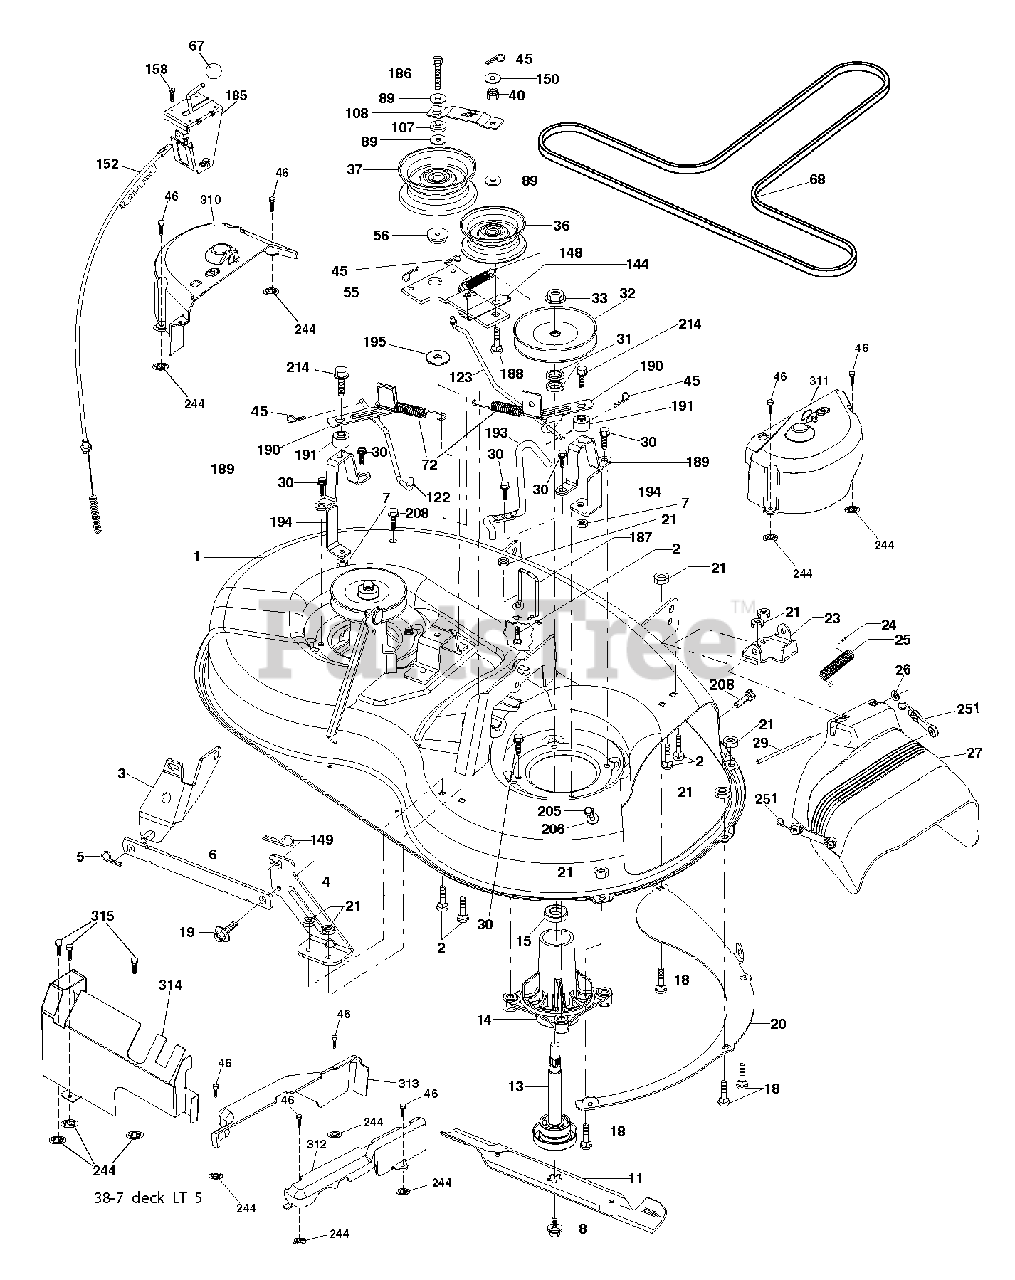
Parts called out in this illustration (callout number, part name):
1	DECK SVC 38/94 192556X431
2	BOLT 5/16-18 X3/4 ZN/YEL GR 5
3	BRKT ASM SWAY BAR
4	BRACKET DECK SWAY BAR 38"/42"
5	Retainer Spring
6	BAR SWAY DECK
7	NUT.71038.31-18.HEX.NYLOCK
8	BOLT.WASHER.ASM.7/16-2
11	BLADE 38" PREMIUM
13	SHAFT.ASM.MDRL.N/GREASE.38
14	HOUSING.MANDREL.4PT.
18	BOLT
19	BOLT SHD 5/16-18
20	BAFFLE.VORTEX.FRONT.38"
21	LOCKNUT
23	BRKT.DEFLECTOR.38"2005+
24	CAP-SLEEVE LT
25	SPRING.TORSION.DEFLECT
26	NUT PUSH M
27	SHIELD ASM.DFLCTR MWR.38-7"BLK
29	ROD.HINGE
30	SCREW, WASHER HEAD
31	WASHER.SPACER.MANDREL
32	PULLEY MANDREL
33	NUT.FLANGE.LOCK.TOP
36	FLAT IDLER PULLEY
37	PULLEY.IDLER.FLAT.UNPLATED
45	RETAINER M
46	SCREW.1/4-20X5/8
56	SPACER.RETAINER.MOWER
67	KNOB T (3/8 HOLE)
68	V-BELT.MOWER.38"2005+
72	SPRING.BRAKE.RETURN.38"
89	WASHER
107	SPACER.IDLER.ARM
108	STIFFENER.IDLER.ARM
122	LINK.BRAKE.38"LEFT.2007
123	LINK.BRAKE.38"RIGHT
144	KEEPER BELT
148	IDLER RETURN SPRING
149	SPRING.RETAINER.YELLOW.ZINC
152	CABLE.CLUTCH.38".SERVICE
158	SCREW
185	HEAD ASM. CABLE CLUTCH
186	SCREW.HXWSH.3/8
187	KEEPER BELT
188	BOLT, CARRIAGE IDLER
189	STAND, BRAKE
190	ARM, BRAKE
191	BRAKE.SPACER.38".DECK
193	KEEPER BELT RH MANDREL
194	GUARD BRAKE
195	WASHER 12/32X2X10GA
205	SCREW
208	SCREW 3/8-16X1/2
214	BOLT/WASHER ASM 5/16-18
244	PALNUT 1/4
251	ELASTIC STRAP KIT
315	SCREW 1/4X20
